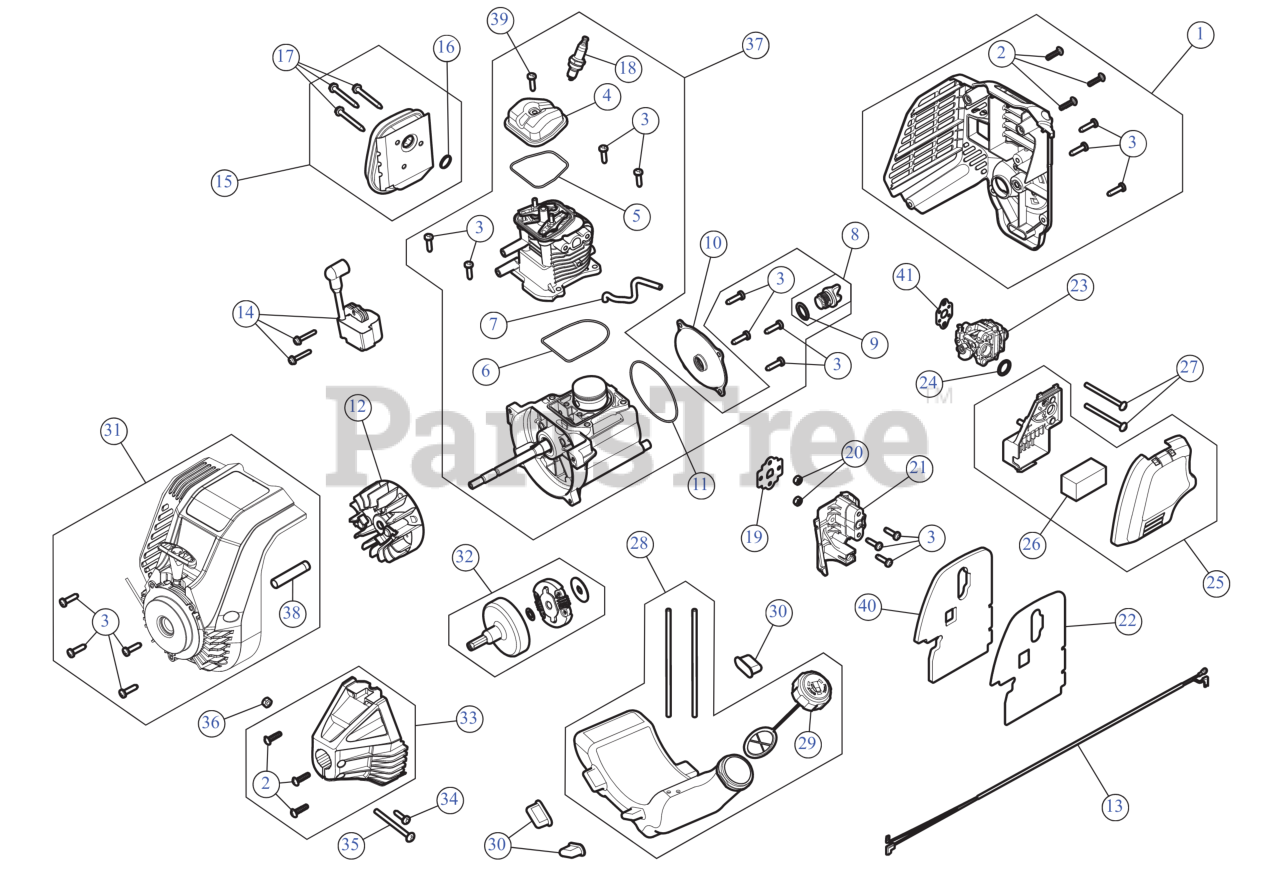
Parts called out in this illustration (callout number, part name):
1	REAR ENGINE COVER
2	SCREW 8-16 x 3/4
3	SCREW, M5 x 18.7MM
4	ROCKER COVER
5	O-RING
6	O-RING CYL AC5
7	HOSE, BREATHER
8	OIL PLUG
9	RING, OIL PLUG (AC
10	CRANKCASE COVER
11	O-RING CRNKCSE CVR
12	FLYWHEEL ASSEMBLY AC3.1
13	LEAD WIRES
14	MODULE ASM
15	MUFFLER ASSEMBLY
16	GASKET/MUFFLER
17	SCREW M5 x 44MM
18	SPARK PLUG 4 CYCL
19	GASKET/INSULATOR
20	NUT 10-32
21	CARB INSULATOR
22	GASKET
23	CARBURETOR
25	AIR CLEANER ASSEMBLY
26	AIR FILTER
27	SCREW 10-32X2.5
28	FUEL TANK ASSEMBLY
29	FUEL CAP ASSEMBLY 43MM-6 W/O HOLE
30	FUEL TANK PADS
31	STARTER HOUSING
32	CLUTCH ASSEMBLY
33	CLUTCH COVER
34	SCREW, 8-32 x .312 P
35	SCREW
36	HEX NUT
37	SHORT BLOCK
38	SPACER :2.165"
39	SCR, VALVE COVER
40	HEAT SHIELD
41	CARBURETOR GASKET
